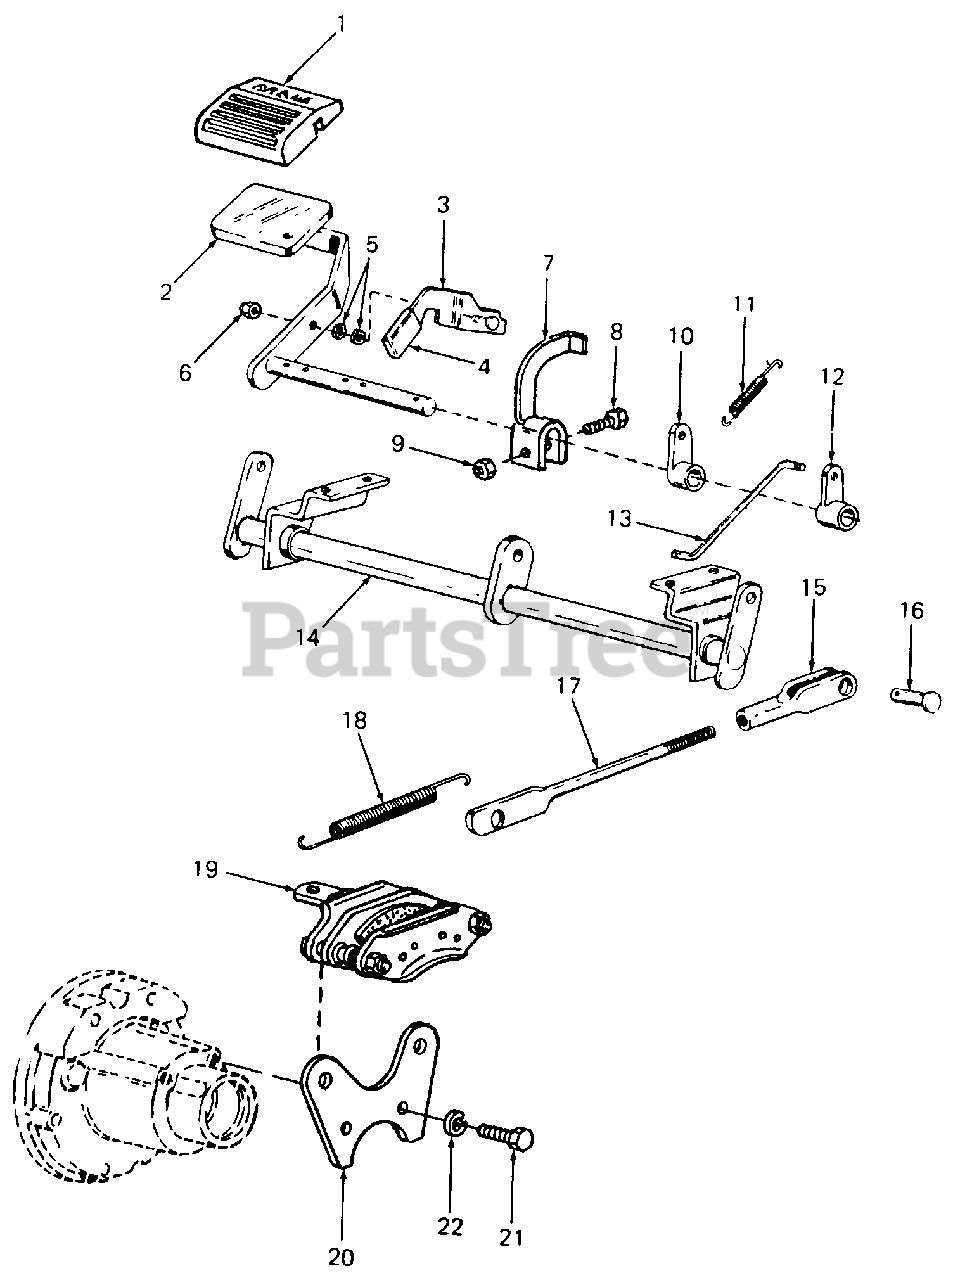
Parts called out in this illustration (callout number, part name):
1	Pad, Brake Pedal
2	Pedal Assy, Brake
5	Washer, Wave, 1/4 Dia
6	Nut, Hex Insert Lock, 1/4-20
9	Nut, Hex Center Lock, 1/4-20
11	Spring, Return
15	Clevis, Adjustment
16	Pin, Clevis, 3/8 Dia X 1.0 Lg
17	Rod, Brake
18	Spring, Tension
19	Kit, Brake Caliper
20	Bracket, Brake Mounting
21	Screw, Hex Cap, 5/16-18 X 1.0 Lg GR5
22	Washer, Lock, 5/16
